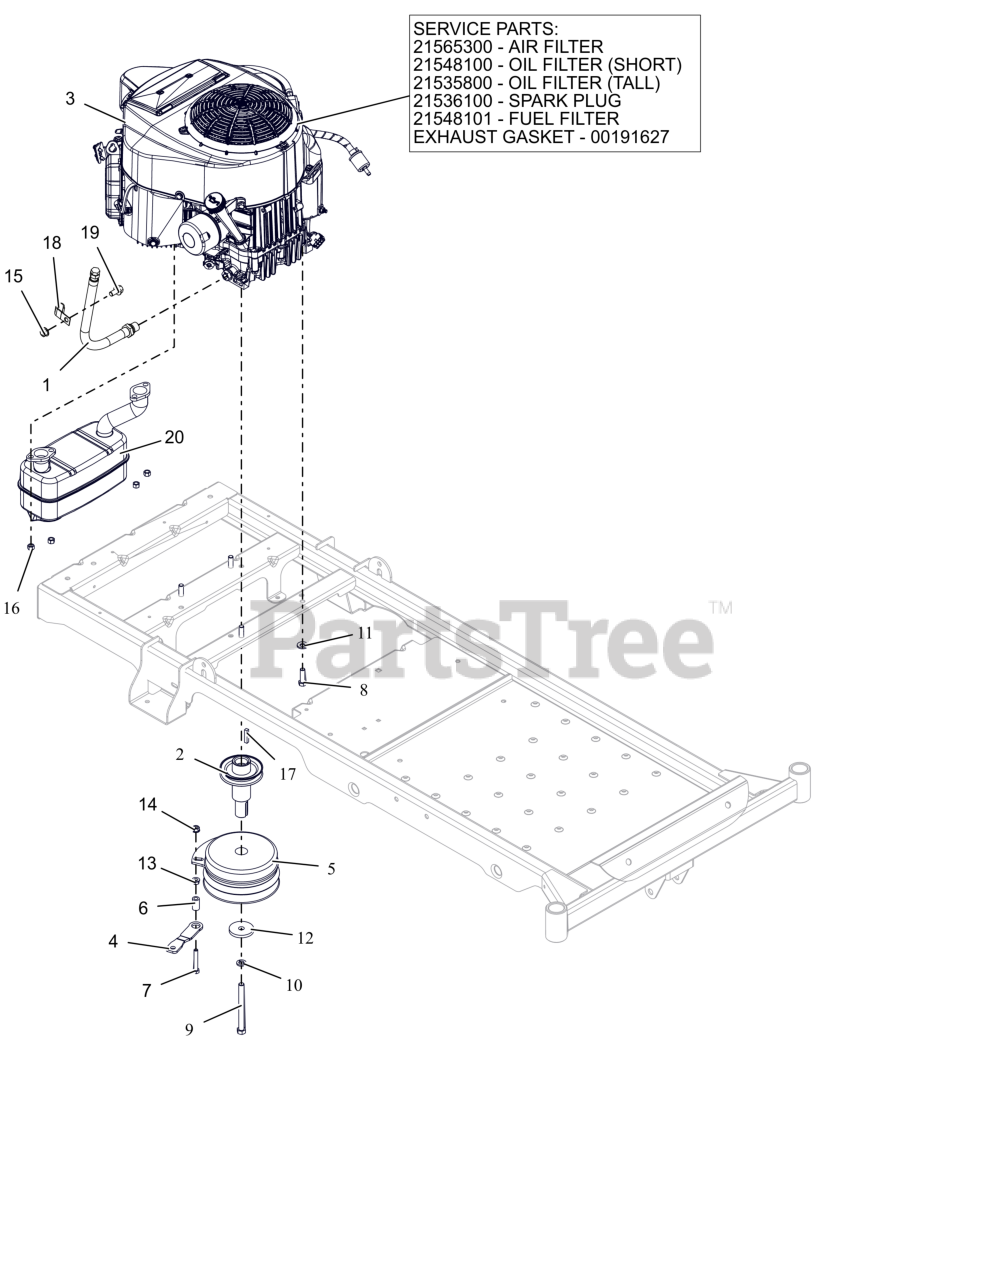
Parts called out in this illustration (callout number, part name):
1	HOSE, OIL DRAIN
2	WLDMT, CRANKSHAFT EXTENSION
3	ENGINE, KAWASAKI FR600
3	AIR FILTER
3	OIL FILTER, KAWASAKI FR
3	FILTER,OIL - KAW
3	PLUG, SPARK
3	FUEL FILTER-KAWASAKI FR
3	GASKET, MUFFLER S/O
4	BRKT, CLUTCH
5	CLUTCH, 105 FT*LB MONO POLE
6	SPACER, RUBBER 5/16 IDX1.0 LG
7	BLT, HEX .31-18X2.00 G5 ZCC
8	BLT, HEX .38-16X1.25 G5 ZCC NT
9	BLT, HEX .44-20X4.50 G8 ZCC NT
10	WSHR, LK-REG .438X.109 ZCC
11	WASHER, 3/8" SPRING DISC
12	WSHR, FLT .469X2.00X.250 ZCC
13	NUT,SPNLK-FLG .31-18 G5 ZCC
14	NUT,LK-CTR-FLG .31-18 GF ZCC
15	NUT-LK-CTR-FLG .375-16 GF ZCC
16	NUT-LK-TOP-FLG M8 ZCC
17	KEY-SQ .25 X 1.25 X .25 SAE
19	BLT, SERHFWH 0.375-16X0.75 GR5 ZCC
20	MUFFLER - KAWASAKI (ZT)
